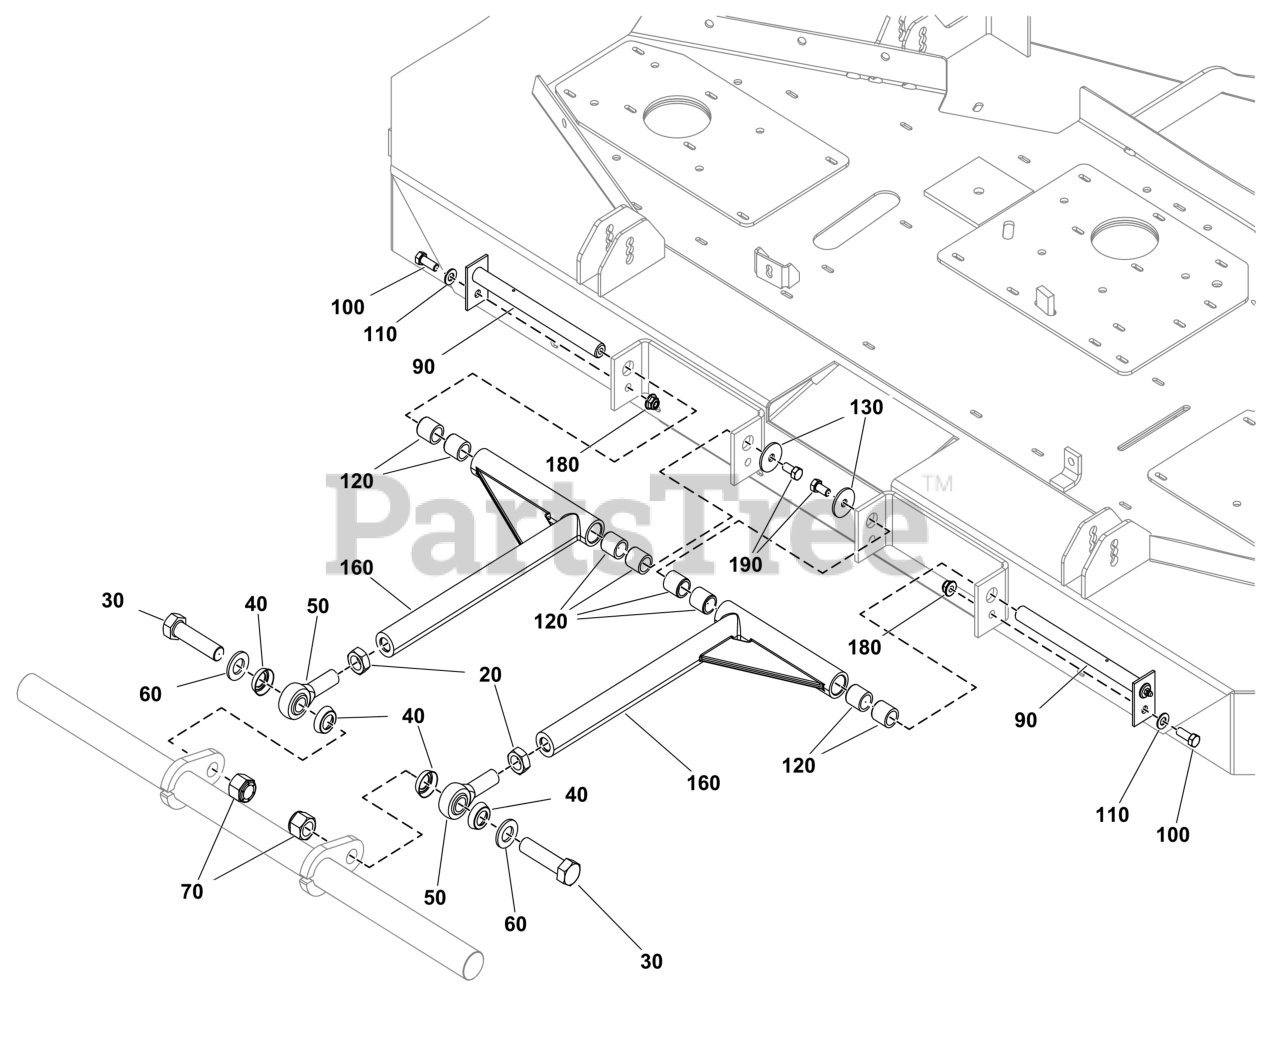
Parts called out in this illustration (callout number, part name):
20	NUT, 3/4-16 HEX JAM
30	BOLT, 3/4-16 X 3" YZ
40	SEAL, 3/4" ROD END
50	BALL JOINT, 3/4-16, M
60	WASHER, 3/4" SAE
70	NUT, 3/4-16 HEX NYLON
100	BOLT, 3/8-16 X 1" GD5
120	BUSHING, .75 X 1.00 X
130	WASHER - .39X1.50
160	PUSH BAR ASSEMBLY
180	NUT, 3/8-16 HEX NYLOCK
190	BOLT - 3/8-16 X 3/4
